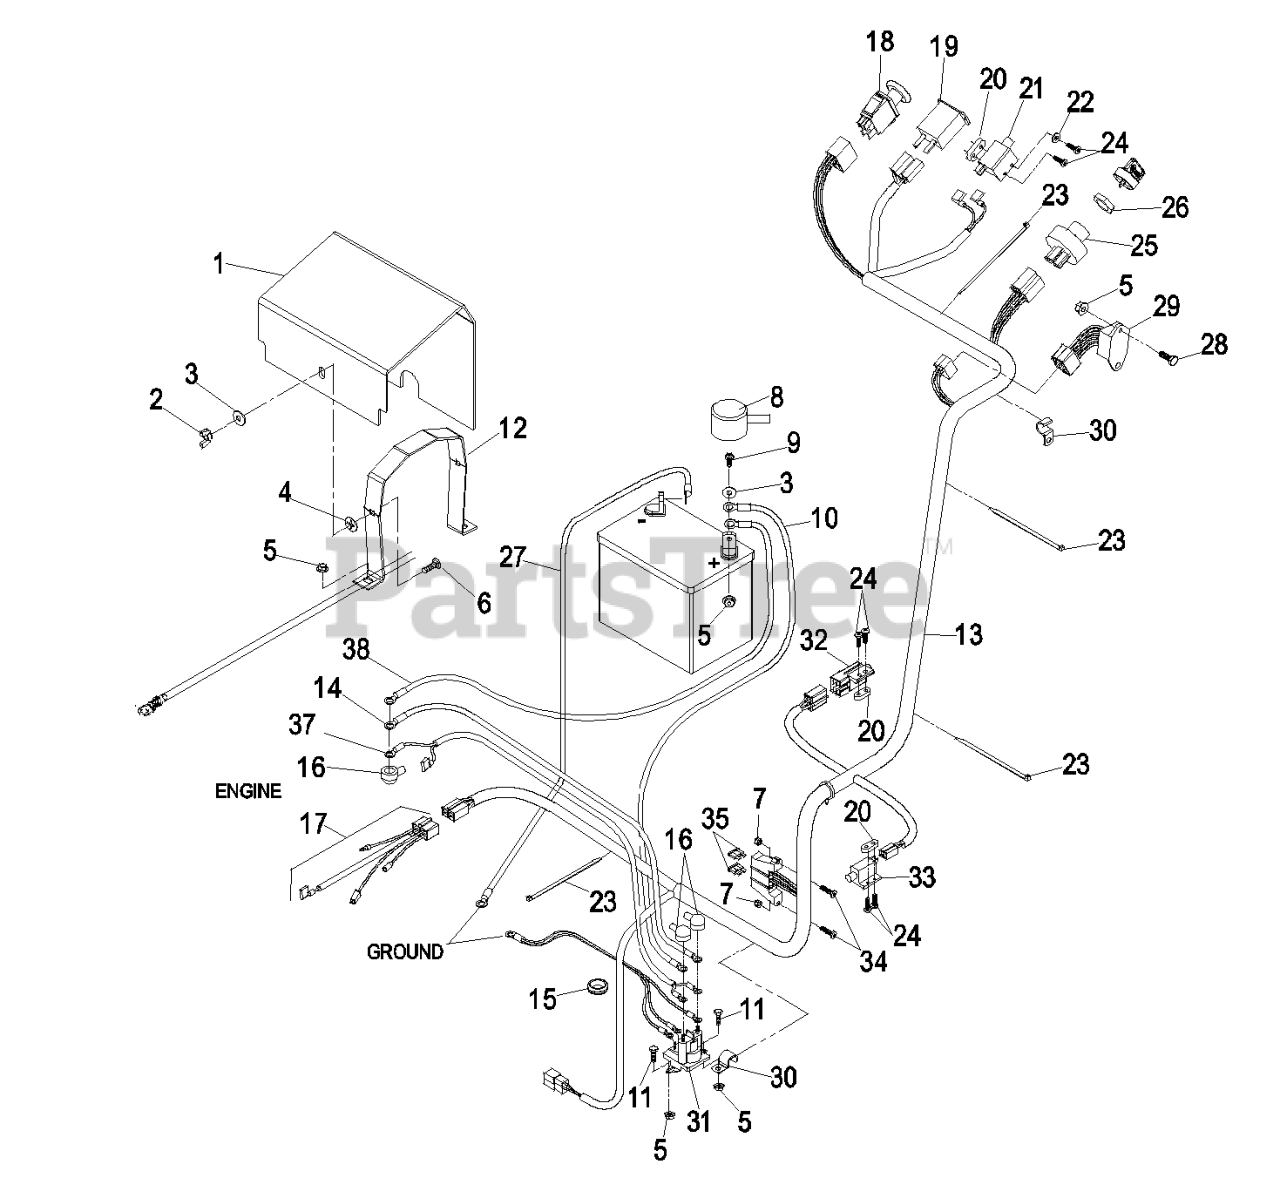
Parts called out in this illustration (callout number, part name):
1	COVER,BATTERY W/DECAL
2	NUT-WING
3	WASHER-FLAT
4	NUT-RETAINING
6	BOLT-CARR
7	NUT-LOCK, NI
8	INSULATOR-BATTERY
9	SCREW-HH
10	POSITIVE BATTERY CABLE AS
11	SCREW-HH
12	STRAP,BATTERY HOLDDOWN
13	HARNESS,TTH ECS WIRING
14	ASM,POSITIVE STARTER CABL
15	GROMMET
16	INSULATOR-SOLENOID
17	HARNESS,WIRING 19KA
18	SWITCH-PTO
19	METER-HOUR
20	PLATE-TAPPED
21	SWITCH-OPEN, NORMALLY
22	WASHER-FLAT
23	TIE-PLASTIC
24	SCREW-PPH
25	SWITCH,IGNITION
26	NUT-SWITCH, IGNITION
27	WIRE-GROUND
28	SCREW-HH
29	MODULE-OPC NO TIME DELAY
30	CLIP-HALF, LOOM
33	SWITCH-CLOSED, NORMALLY
34	SCREW-HEAD, TRUSS
35	FUSE-BLADE TYPE, 20 AMP
36	NUT-LOCK, NI
37	ASM,HARNESS TT20KCE
38	POSITIVE BATTERY CABLE AS
